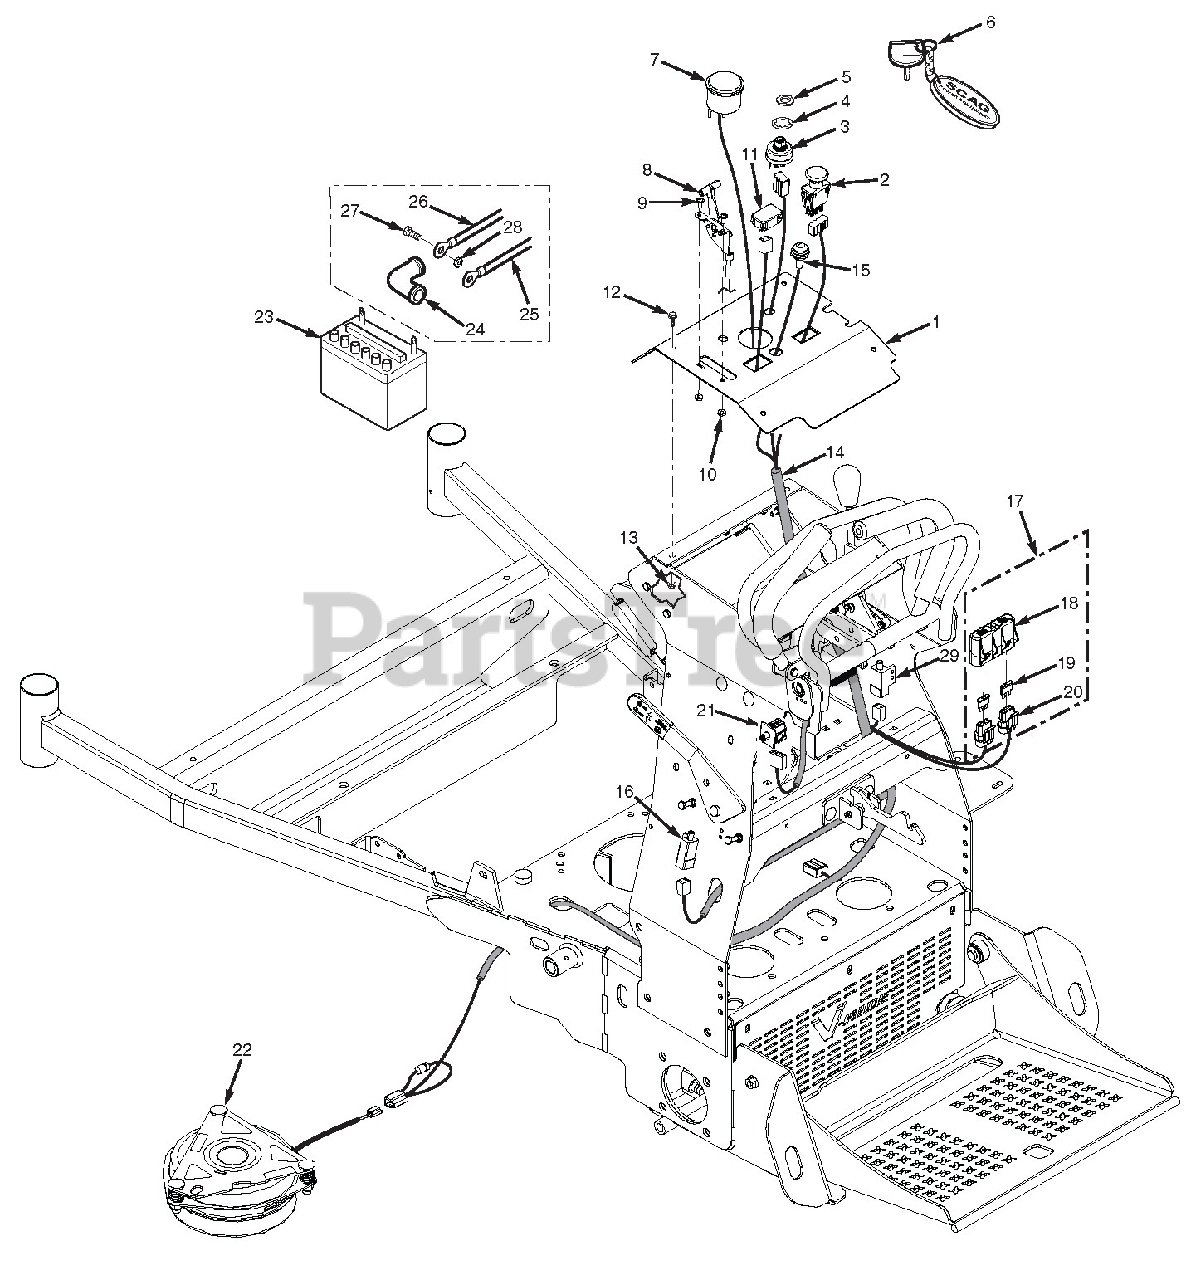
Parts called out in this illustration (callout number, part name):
1	Instrument Panel w/Decal
2	Switch, PTO - 10 Amp
3	Key Switch
4	Lockwasher, 5/8" Internal Tooth
5	Nut, 5/8-32 Special
6	Key Chain w/ Keys
6	Key w/Shroud
7	Voltmeter
8	Throttle Control, SVR
9	Bolt, Carriage #10-24 x 1/2"
10	Locknut, #10-24
11	Hourmeter
12	Bolt, Hex Head 1/4-20 x .63
13	Nut, Serrated Flange 1/4-20
14	Wire Harness, SVR
15	Indicator Light Assembly
16	Switch, Interlock
17	Double Fuse Assy.
18	Cover, Sealed Double
19	Fuse, 20 Amp
20	Fuse Holder
21	Switch, Double Pole - Plunger
22	Clutch w/Tag (36A, 48V, 52V)
22	Clutch w/Tag (61V)
23	Battery (not avail. through Scag)
24	Rubber Boot
25	Cable, Battery Black 18"
26	Cable, Battery Red 18"
27	Bolt, Hex Head 1/4-20 x 3/4"
28	Nut, 1/4-20
29	Switch, Interlock
